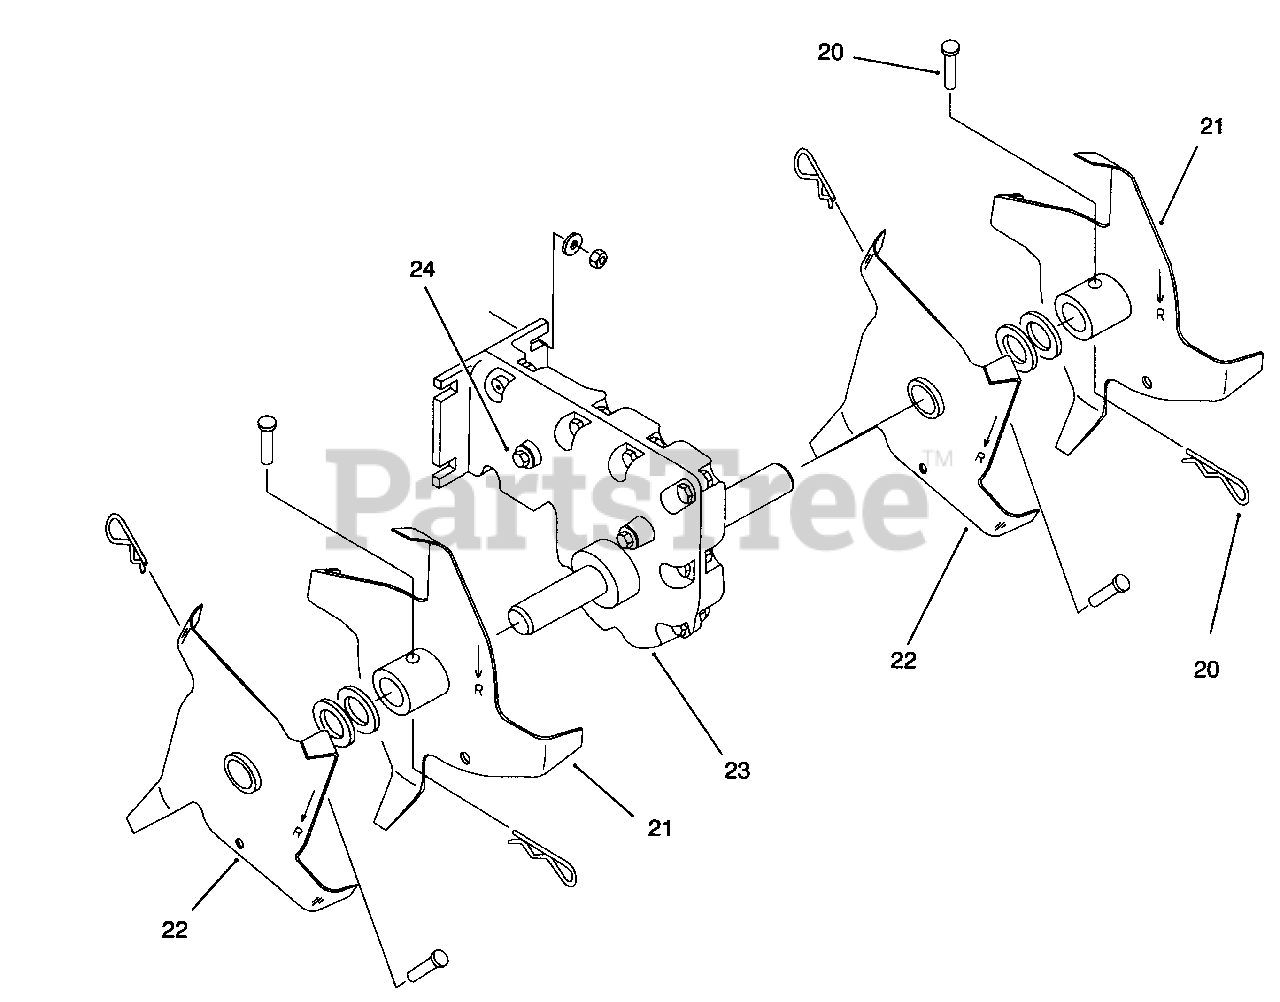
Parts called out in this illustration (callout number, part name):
20	Tine Fastener Asm.
21	Tine Asm. (Left Outer, Right Inner)
22	Tine Asm. (Left Inner, Right Outer)
23	Gear Box Asm.
24	Retainer Bolt Sleeve Asm.
